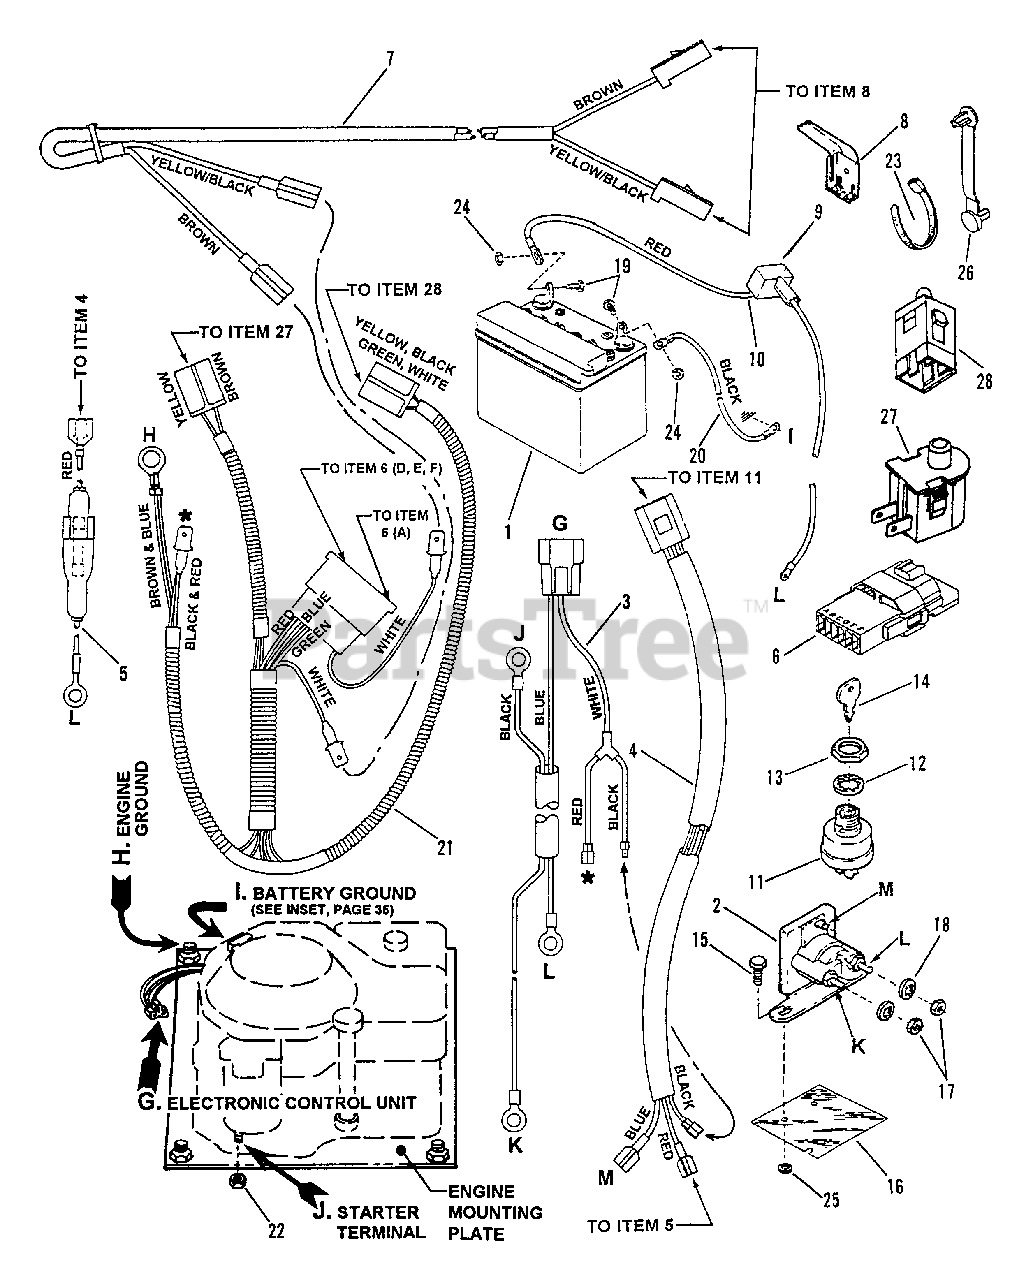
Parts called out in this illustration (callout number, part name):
1	KIT, 12V Dry Charge Battery
2	SOLENOID
3	HARNESS, Starter Wiring
4	HARNESS, Ignition Wiring
5	HOLDER, Fuse
6	INTERLOCK Module
7	HARNESS, (Deck Interlock Wiring)
8	SWITCH, Deck Interlock
9	COVER, Battery Cable
10	CABLE, Positive (Red)
11	SWITCH, Ignition (Includes keys #11138)
12	WASHER, 5/8 Internal Tooth Lock
13	NUT, 5/8-32 Hex
14	KEY, Switch
15	SCREW, 1/4-20 x 1/2" Self-Tapping
16	PROTECTOR, Solenoid
17	NUT, 1/4-20 Hex
18	WASHER, 1/4 Internal Tooth Lock
19	SCREW, 1/4-20 x 5/8" Hex Head Cap
20	CABLE, Negative
21	HARNESS, Operator Presence Control Wire
22	NUT, 1/4-20 Hex
23	TIE, 7" Long Cable
24	NUT, 1/4-20 Hex Lock
25	RETAINER, 1/4 Bolt
26	TIE, 2" Long Cable
27	SWITCH, Seat (NC - Gray)
28	SWITCH, Operator Presence Control Traction
